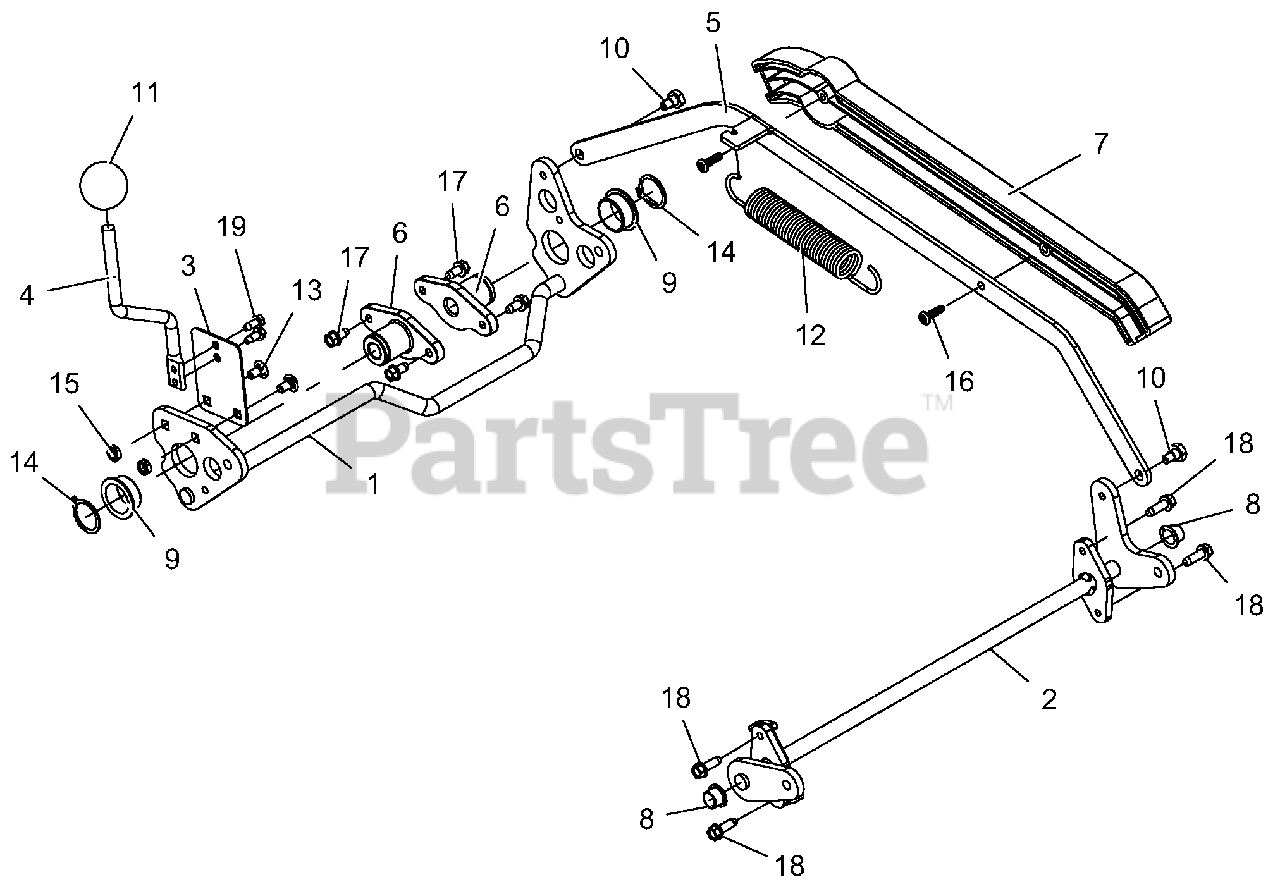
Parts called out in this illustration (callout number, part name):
1	WLDMT, LM REAR AXLE
2	WLDMT, LM FRONT AXLE
3	PLATE, HOC SPRING
4	LEVER, HOC ADJUST
5	LINK, HOC CONNECT
6	HUB, LM REAR AXLE
7	COVER, LINK ROD
8	BUSHING, POLYLINER - .50 SPLIT
9	BSHG, FLANGE 1.0 x 1.125 x .50 x 1.375
10	BOLT, SHLDR .320 x .210 x .25-20 SELF-TAPPING
11	KNOB, BALL - BLACK 1.47" .375-16
12	SPRG, EXTENSION
13	BLT-RDHDSQNK .25-20 x .50 G5 Y
14	RG-RTNG-EXT 1.00 x .042
15	@NUT-LK-CTR-JAM .25-20 YWZC
16	SCR-TAP #12-14 x .75 PLASTITE BLZC
17	SCR-TAP .25-20 x .50 HWH TR YWZ
18	SCR-TAP .25-20 x .75 HWH TR YWZ
19	SCR-TAP 12-24 x .50 HWH TR YWZC
